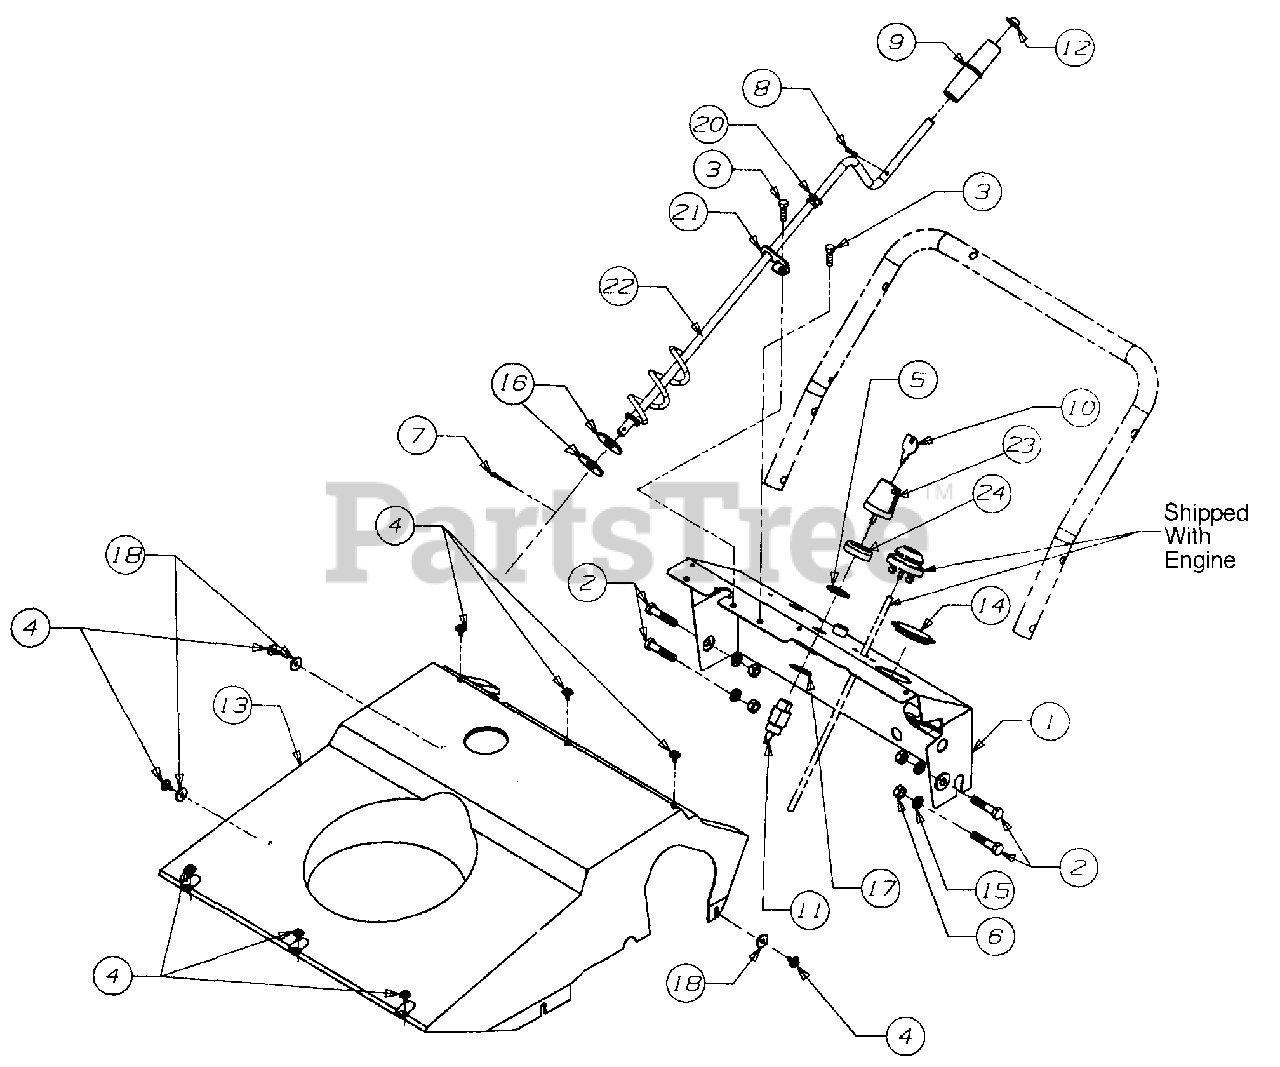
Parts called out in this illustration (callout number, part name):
2	Screw - Hex
3	Screw - Hex Tap
4	Screw - Hex Tap
6	Nut - Hex
7	Pin - Cotter
8	Pin Roll
9	Knob - Chute Crank
10	Key - Ignition - Std.
11	Switch - Key
13	Shroud - Grey
14	Plug
15	Washer Lock
17	Washer Internal Lock
18	Washer Flat
20	Bushing
21	Bracket Chute Crank
22	Crank Ass'y. Chute
23	Key - Ignition w/Bell Cover
24	Cover - Ignition Switch
